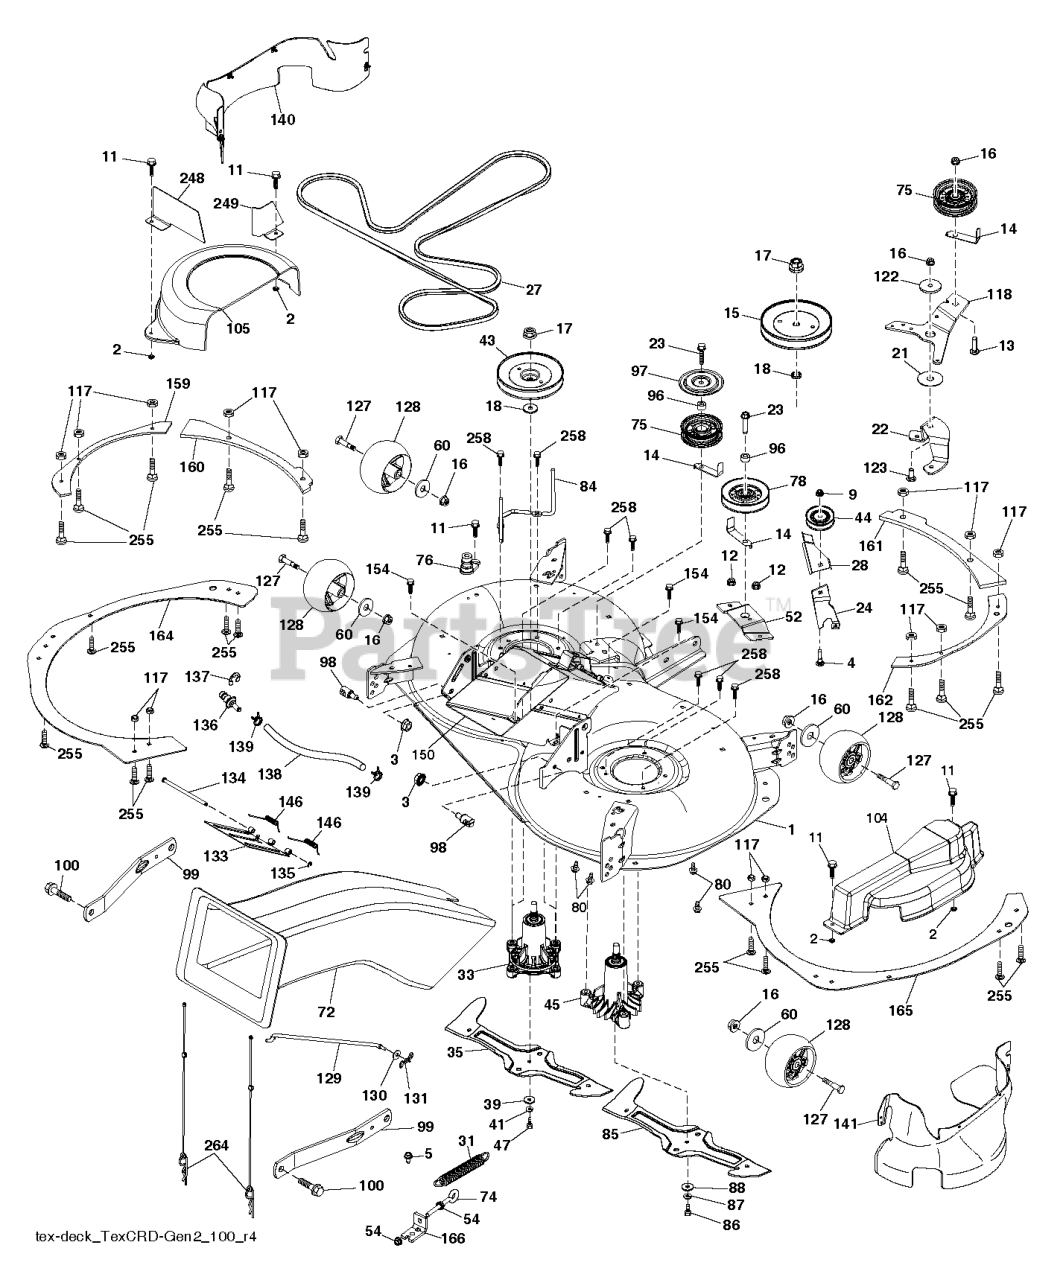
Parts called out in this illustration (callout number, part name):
1	KIT.SVC.DECK.WELD.107HP.EL.498
2	PALNUT 1/4
4	BOLT.CARRIAGE.5/16-18
5	BOLT.5/16HEX.WHS.HD
9	NUT HEX FLG NYLOCK BLK 5_16-1
11	SCREW.1/4-20X5/8
12	NUT HEXAGON FLANGE 5/16-18 ST
13	GSPW Bolts
14	KEEPER, BELT IDLER
15	PULLEY.MANDREL.5.438.P
16	NUT LOCK FLG 3/8-16 UNC
18	WASHER.SPACER.MANDREL
22	BRACKET CRD IDLER ARM MOUNT BL
23	BOLT;HEX_3/8-16 X 1.78.CLRZINC
24	BRACKET 107 CRD ANGLED V-IDLER
27	BELT 107 CRD DECK DRIVE BELT
28	KEEPER 107 CRD ANGLED IDLER KE
31	SPRING.EXTN.42.FCS.TR.DECK.DRV
33	KIT.MANDREL.NONGREASE.TALL
35	BLADE.3N1.LH.CRD
39	WASHER.7/16.FLAT
43	PULLEY PULLEY MANDREL 5.438 PD
44	PULLEY.V-IDLER.
45	MANDREL ASM.CRD RH 6PT STAR
47	SCREW.SEMS.7/16-20X1.HEX.HEAD
52	BRACKET 107 CRD CENTER V-IDLER
54	GSPW Hardware
72	CHUTE.SLOTTED.HOLES.TEX.CRD.II
74	GSPW Bolts
76	1/2" BARB.DECK.WASHOUT.PORT
78	PULLEY.IDLER.4.25
80	GSPW Bolts
84	KEEPER KEEPER. LH MANDREL BELT
85	BLADE.3N1.RH.CRD
86	BOLT.3/8-24X1.25GR8. LHTHRD
88	WASHER.BLADE
96	SPACER
97	PROTECTOR
98	STUD.W/"D"ANTI-ROTATION
99	ARM.SUSPENSION.MOWER.R
100	BOLT.SHOULDER
104	COVER.MANDRE.107.CRD.VAC.GUARD
105	COVER.MANDREL.107.LH.GEN.2
117	NUT T
118	ARM 107 CRD CLUTCHING ARM BLAC
122	SPACER.RETAINER.MOWER
128	WHEEL.GAUGE.RALLY
129	ROD ROD. SWAY CRD GEN II
131	PIN.COTTER.5/16.BOW TI
133	COVER DOOR.107 CM CRD EZ MULCH
135	E-RING.5/16"
136	PLUG WASHOUT PORT HOOKUP
138	HOSE 107 CRD WASHOUT PORT HOSE
140	GUARD.ASSEMBLY.107.LH.FRENCH
141	GUARD.ASSEMBLY.107.RH.FRENCH
146	SPRING SPRING: EZ MULCH DOOR
150	CHUTE LOWER.WLDT.107.CRDII
154	SCREW T-30 1/4-20 X
159	REINFORCE.PLATE.LH.FT.X431
160	REINFORCE.PLATE.LHS.BOLT.431
161	REINFORCE.PLATE.RH.FRT.X431
162	REINFORCE.PLAT.RH.SD.BLT.X431
164	BAFFLE.PLATE.PNT.107CRD.LT.BLK
165	BAFFLE.PNT.107.CRD.PLATE.RT.BK
166	BRACKET CRD ELEC DECK DRIVE TE
248	GUARD BELT.CRD.LH.REAR.ISO X43
249	GUARD BELT.CRD.LH.FRNT.ISO X43
255	BOLT CUP HEAD SQUARE NECK 1/4-
258	BOLT.HEX.WASHR.HED.313-18X1.19
